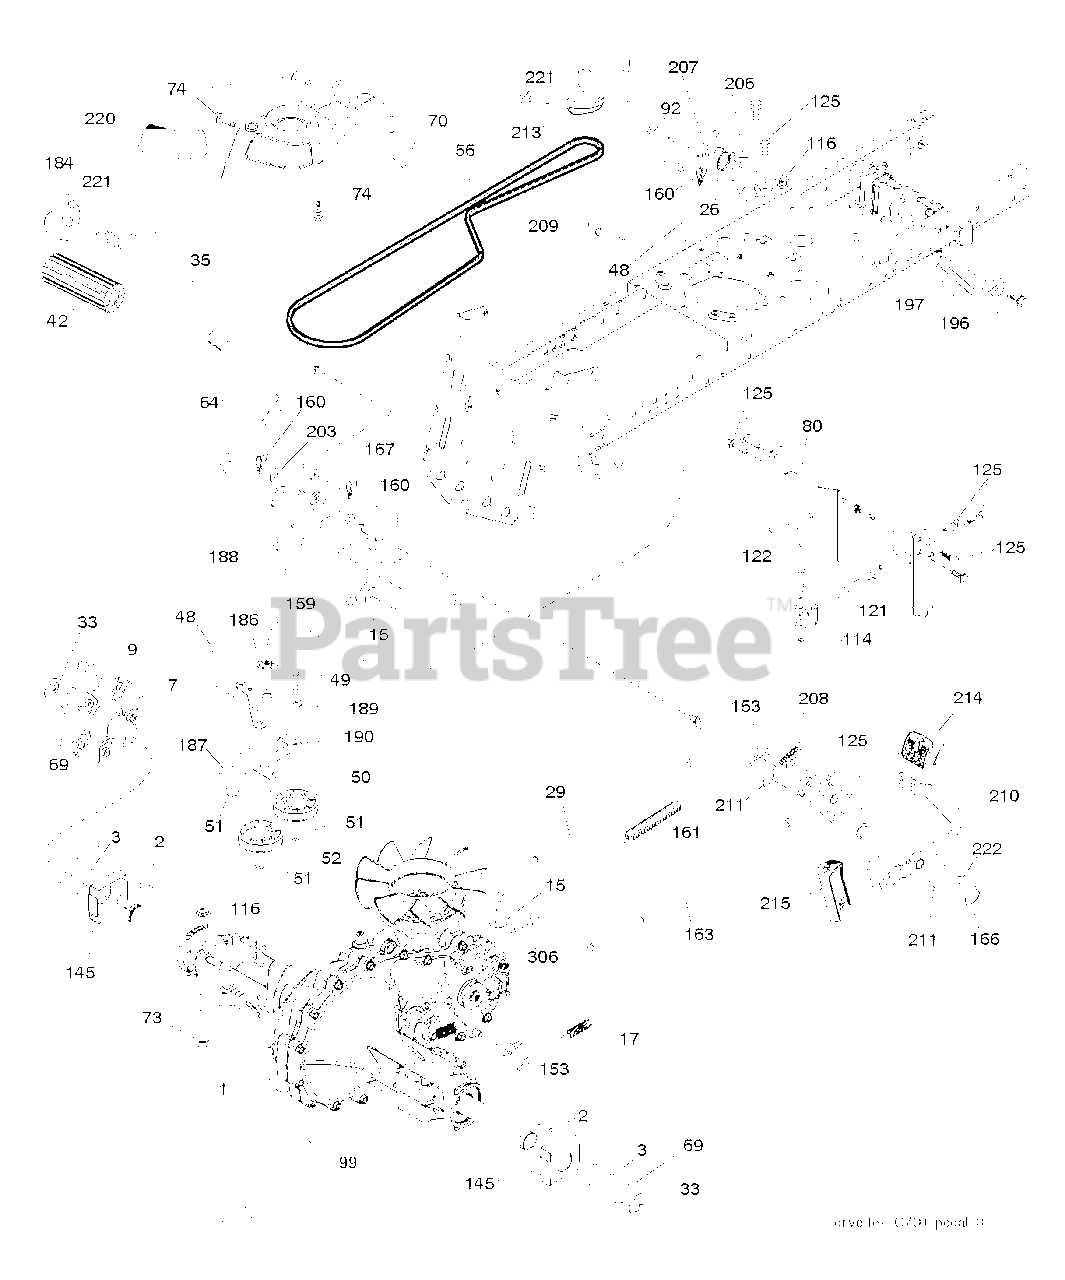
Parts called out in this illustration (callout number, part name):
2	KEY 1/4 X 2.5
7	HUB.ASM.WHEEL.REAR.23"TEX
15	WASHER
17	SPRING.BRAKE.HG3000/3500
26	SPRING.RETURN.CRUISE
33	E RING HYT
35	ROD.BRAKE.PARTK.HUSQ.TEX
42	PEDAL COVER T
48	BOLT.3/8-16X1.50
50	IDLER.FLAT.910.OFFSET
51	NUT LOCK FLG 3/8-16 UNC
52	IDLER.V-GROOVE.910.OFFSET
56	V-BELT.GROUND.DRIVE.
64	SHAFT.ASM.PEDAL.BRK.CNTR
70	CONSOLE.ASM.RH.GT.FC.HUSQ
73	BOLT HEX FLGHD 5/16-18X3 GR. 5
74	SCREW.HI-LO.CONSOLE
80	STRAP.TORQUE.YT.G700
92	BOLT
99	SPRING.BYPASS.YT.G700
114	NUT.71038.31-18.HEX.NYLOCK
116	NUT LOCK HEX FLANGE 5/16-18
121	BRACKET STRAP TORQUE
122	BOLT.5/16-18X2.5
125	SCREW
145	WASHER.AXLE.FLANGE.HG-3000
153	RETAINER M
159	COTTER PIN
160	RETAINER CLIP
161	SPRING, RETURN LT
163	ROD PEDAL CONTROL
166	NUT.PUSH.625
167	LATCH.BRAKE.SPRING
184	RB HANDLE.PARKG.BRK.HUS/PRED
186	SPACER.RETAINER
187	WASHER 12/32X2X10GA
188	RP LINK.CLUTCH.GROUND.DRIVE
189	BELLCRANK.GROUND.DRIVE.TRAPPED
190	KEEPER BELLCRANK ROUND DRIVE
196	SCREW 3/8-16X1
197	BRKT.ANIT-ROTATION.CLUTCH
203	WASHER
206	BRKT.MOUNT.LATCH.CRUIS
207	LATCH.CONTROL.CRUISE
208	GEAR.SECTOR.CONTROL.CR
209	ROD.CONTROL.CRUISE.GT.
210	ROCKER.ASM.PEDAL.CONTR
211	BEARING.NYLON
213	KNOB.CONTROL.CRUSIE.HU
214	PEDAL.FORWARD.PAD.TEX
215	PEDAL.REVERSE.TEX.GT.4
220	REFLECTOR.RH.TEX GT
221	RETAINER.SPRING.CLIP.H
222	WASHER 21/32 X 1-1/4 X 10 GA.
306	PIN COTTER
